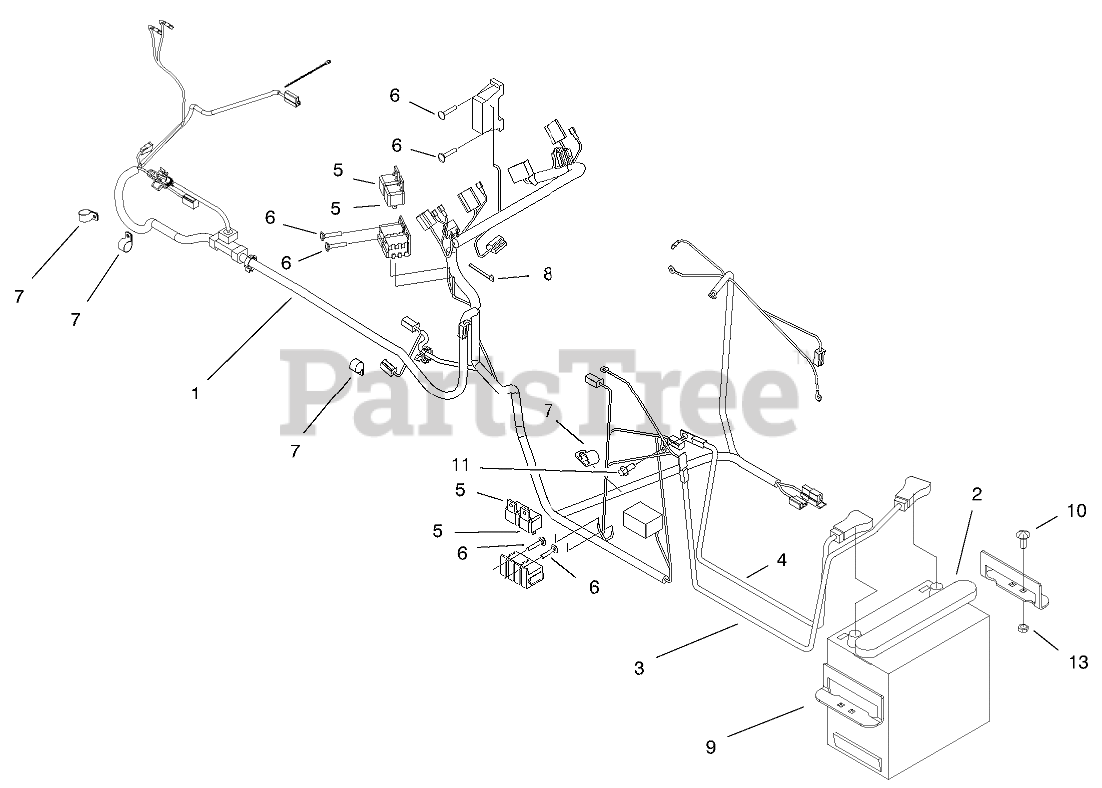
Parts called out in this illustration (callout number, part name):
1	HARNESS - MAIN DS
2	BATTERY - 495CCA
3	CABLE - BATTERY,RED
4	CABLE - BATTERY,
5	RELAY
6	SCREW
7	CLAMP - R
8	TIE-CABLE
9	HOLD - DOWN, BATTERY
10	BOLT-CARR
11	SCREW-HHF
12	TIE-CABLE
13	NUT-LOCK, NI
